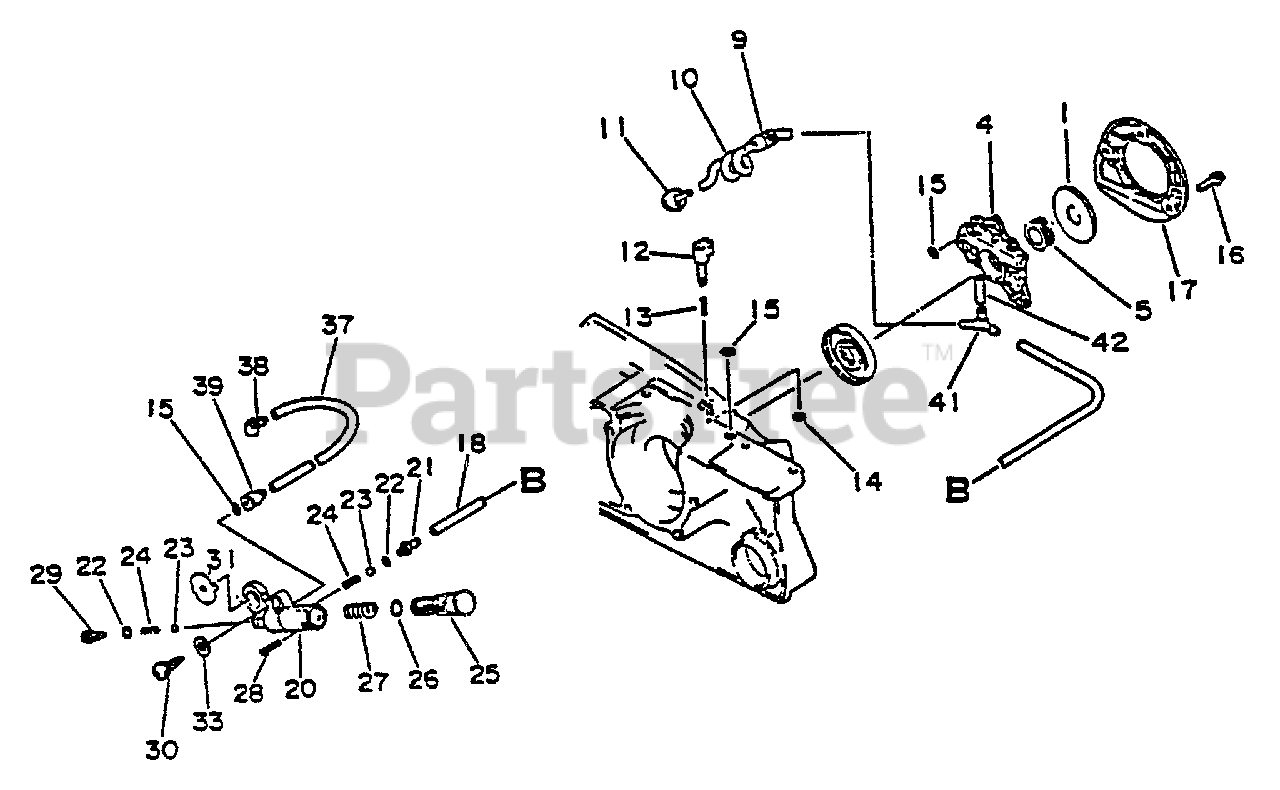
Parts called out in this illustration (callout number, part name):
1	GEAR - WORM
4	AUTO-OILER ASSY
5	GEAR - WORM
10	PIPE - OIL
11	FILTER, OIL
12	DIAL, AUTO-OILER
14	RING, RETAINING - 3
15	O-RING - 3
16	SCREW - 4X14
17	COVER, OIL PUMP
18	PIPE - OIL
20	BODY, OIL PUMP
23	VALVE, BALL
24	SPRING, VALVE
25	PISTON, OIL PUMP
26	O-RING - 7
28	PIN - SPRING -- 2X16
29	ADAPTER, OIL PUMP
30	SCREW - 5X20
31	BRACKET, OIL PUMP
33	WASHER - 5
37	PIPE, OIL - 3X6X125
38	CONNECTOR, PIPE
39	CONNECTOR, PIPE
41	PIPE - 3X6X20 -- BLACK
42	CONNECTOR, PIPE
